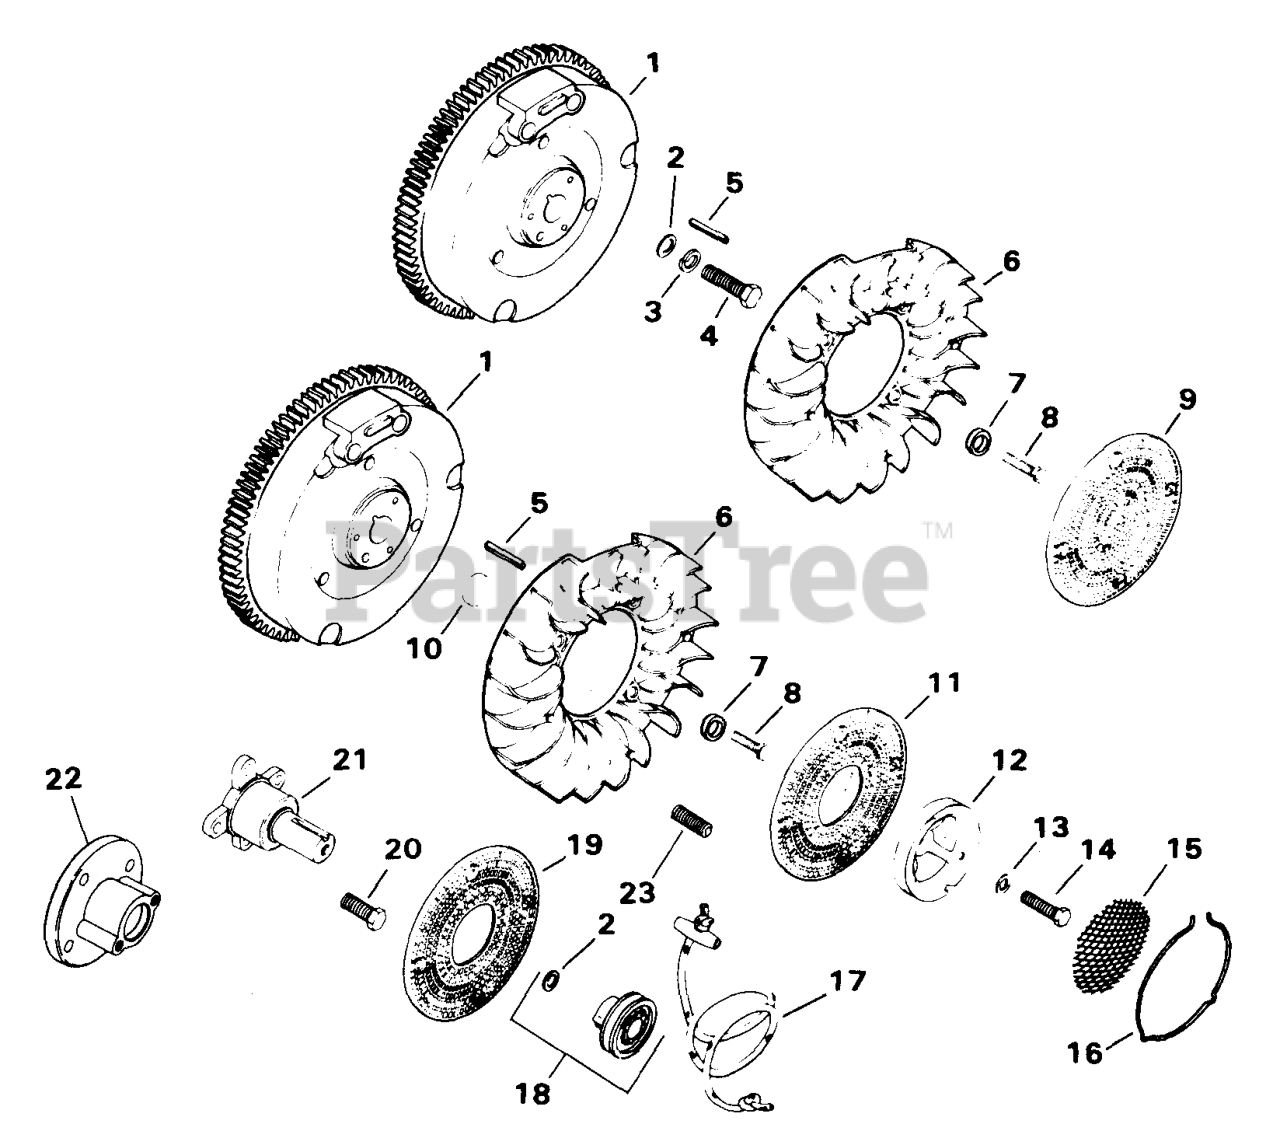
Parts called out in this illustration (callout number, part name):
1	Flywheel
2	Washer, Flat 3/8" I.D., 1-3/8" O.D. X 1/4"
4	Screw, Hex. Mach. 3/8-24x1-1/4"
5	Key, Square 7/8x3/16x3/16"
7	Spacer 1/8"
8	Screw, Hex. Wash. Hd. 1/4-20x5/8"
9	Screen, Grass
